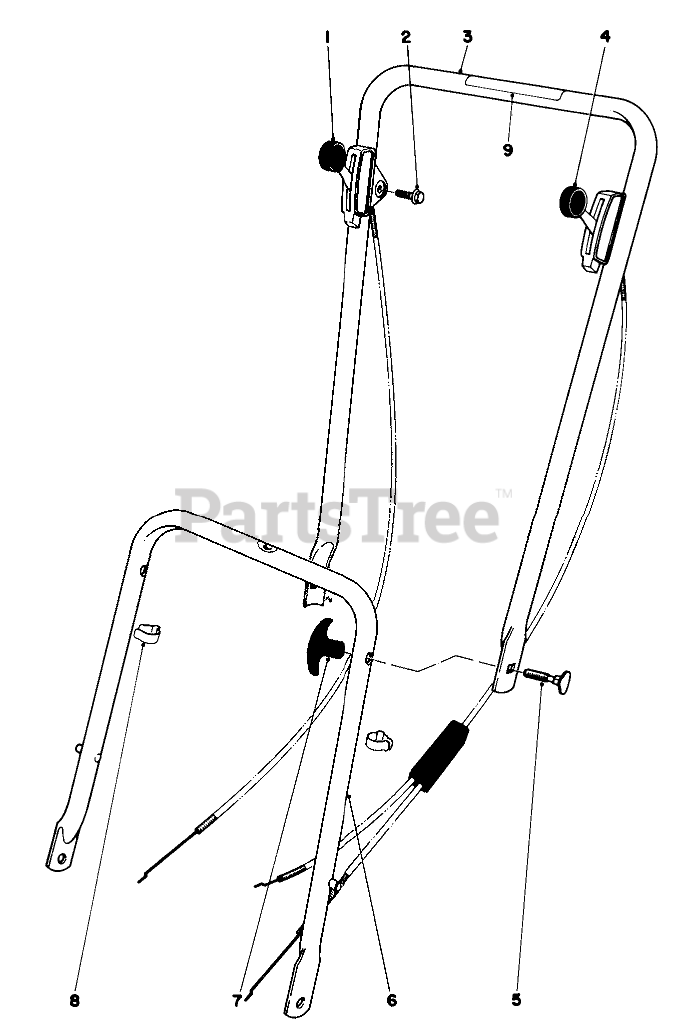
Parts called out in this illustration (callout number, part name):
1	Throttle Control
3	UPPER HANDLE
4	Traction Control
5	HANDLE SCREW
6	Lower Handle
9	Decal
